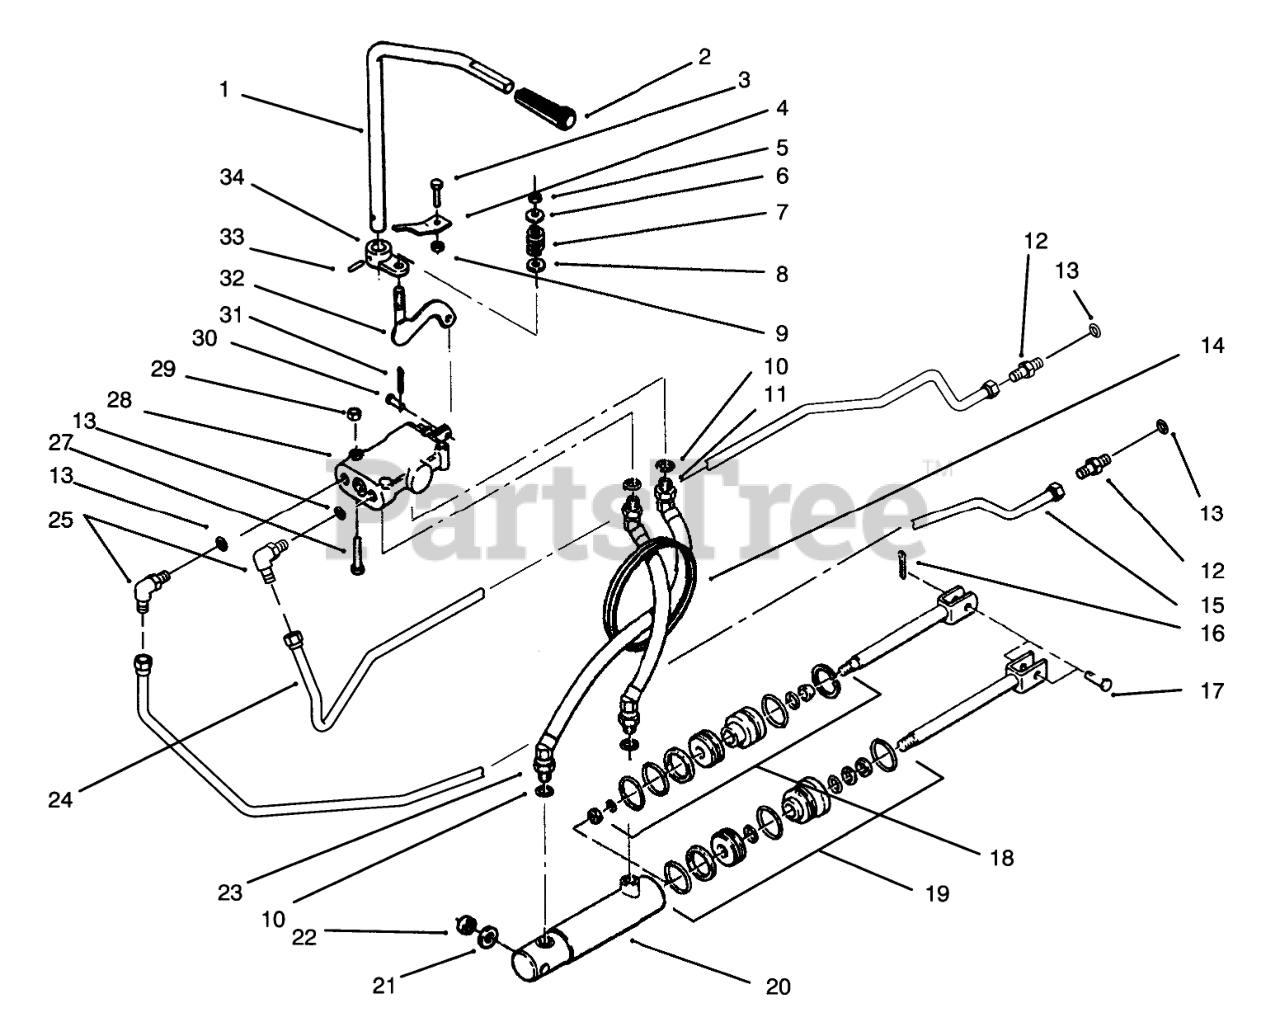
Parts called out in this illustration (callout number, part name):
1	ROD-LIFT CONTROL
2	KNOB-HYDRAULIC LIFT
3	SCREW-HH
4	BRACKET-CONTROL R B
5	NUT-LOCK, NI
7	SPRING
8	SCREW-HH
9	NUT-LOCK, NI
10	O RING
11	Hose ASM-Hydraulic
12	Fitting-Straight (Incl. Ref. #13)
13	0-Ring
14	GROMMET
15	TUBE-HYD PRESSURE
16	PIN-COTTER
17	CLEVIS PIN
18	S/A O-RING&GASKET AS
19	S/A 108872 HYD CYL
20	Cylinder-Hydraulic (Incl. Ref. #18-19)
21	SPACER
22	WASHER
23	Hose ASM-Hydraulic
24	TUBE-HYD RETURN
25	ELBOW
27	SCREW-HH
28	Valve-Hydraulic (Incl. Ref. #30-31)
29	NUT-LOCK, NI
30	Pin
31	Cotter Pin
32	WLDMT-LIFT BAR
33	SPIROL PIN 7/32X7/8
34	ARM-CONTROL
